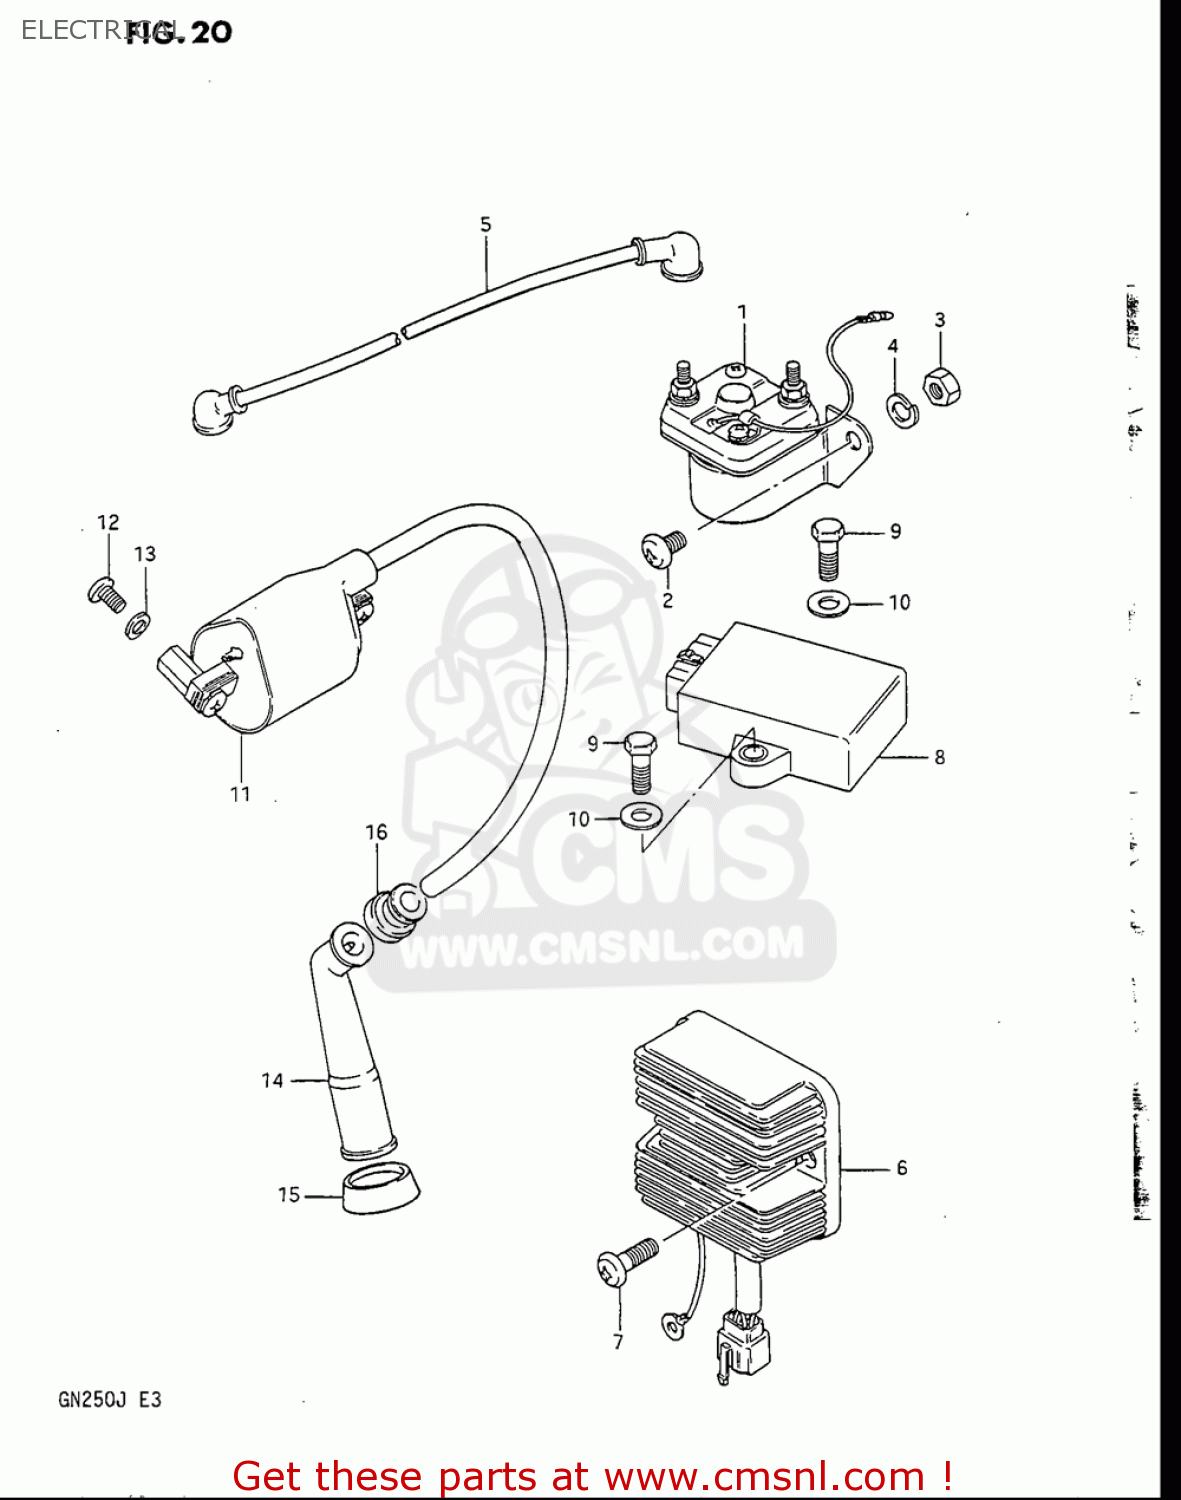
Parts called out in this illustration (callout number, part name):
1	RELAY ASSY,STARTING MOTOR
2	SCREW
3	NUT
4	WASHER,LOCK
5	WIRE,STARTER MOTOR
6	RECTIFIER ASSY
7	SCREW(6X12)
8	IGNITOR UNIT
9	BOLT
10	WASHER
11	COIL ASSY,IGNITION
12	SCREW
13	WASHER
14	CAP ASSY,SPARK PLUG
15	SEAL,SPARK PLUG
16	SEAL,HIGH TENSION CORD
